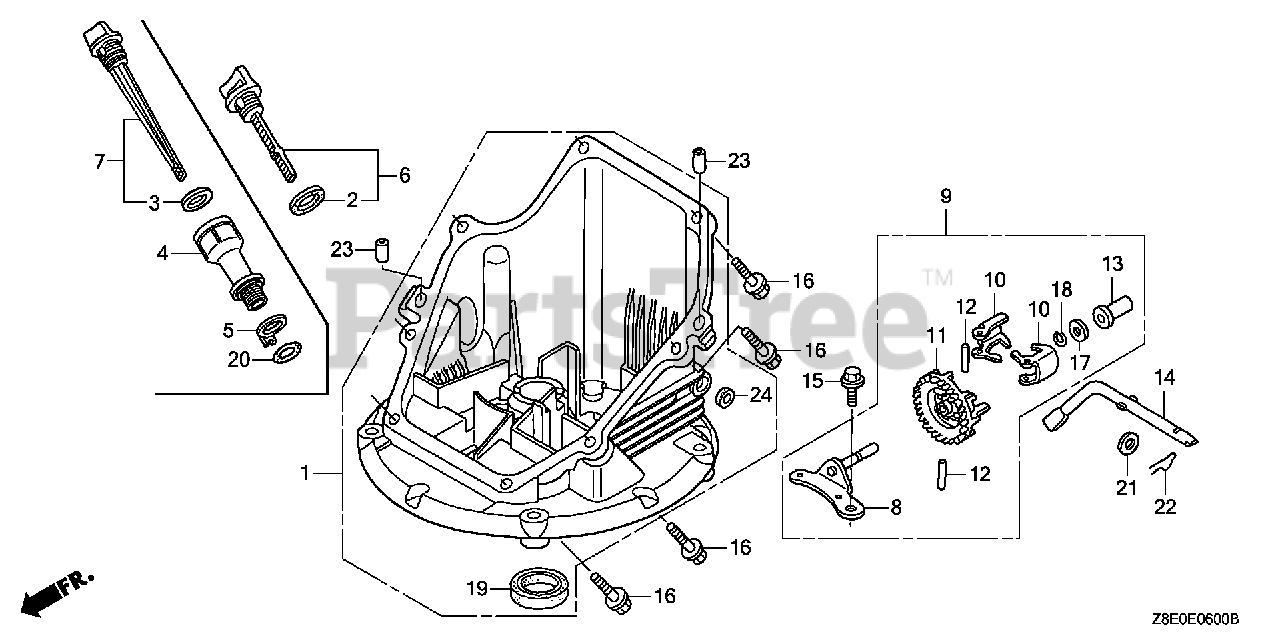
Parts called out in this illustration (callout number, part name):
1	PAN ASSY., OIL
2	GASKET, OIL FILLER CAP
6	GAUGE ASSY., OIL LEVEL
8	SHAFT, GOVERNOR HOLDER
9	GOVERNOR ASSY.
10	WEIGHT, GOVERNOR
11	HOLDER, GOVERNOR WEIGHT
12	PIN, GOVERNOR WEIGHT
13	SLIDER, GOVERNOR
14	SHAFT, GOVERNOR ARM
15	BOLT, FLANGE (6X14) (CT200)
16	BOLT, FLANGE (6X25) (CT200)
17	WASHER, THRUST (6MM)
18	CLIP, GOVERNOR HOLDER
19	OIL SEAL (28X41.25X6) (NOK)
21	WASHER, PLAIN (6MM)
22	PIN, LOCK (8MM)
23	PIN, DOWEL (8X20)
24	OIL SEAL (6X11X4) (ARAI)
